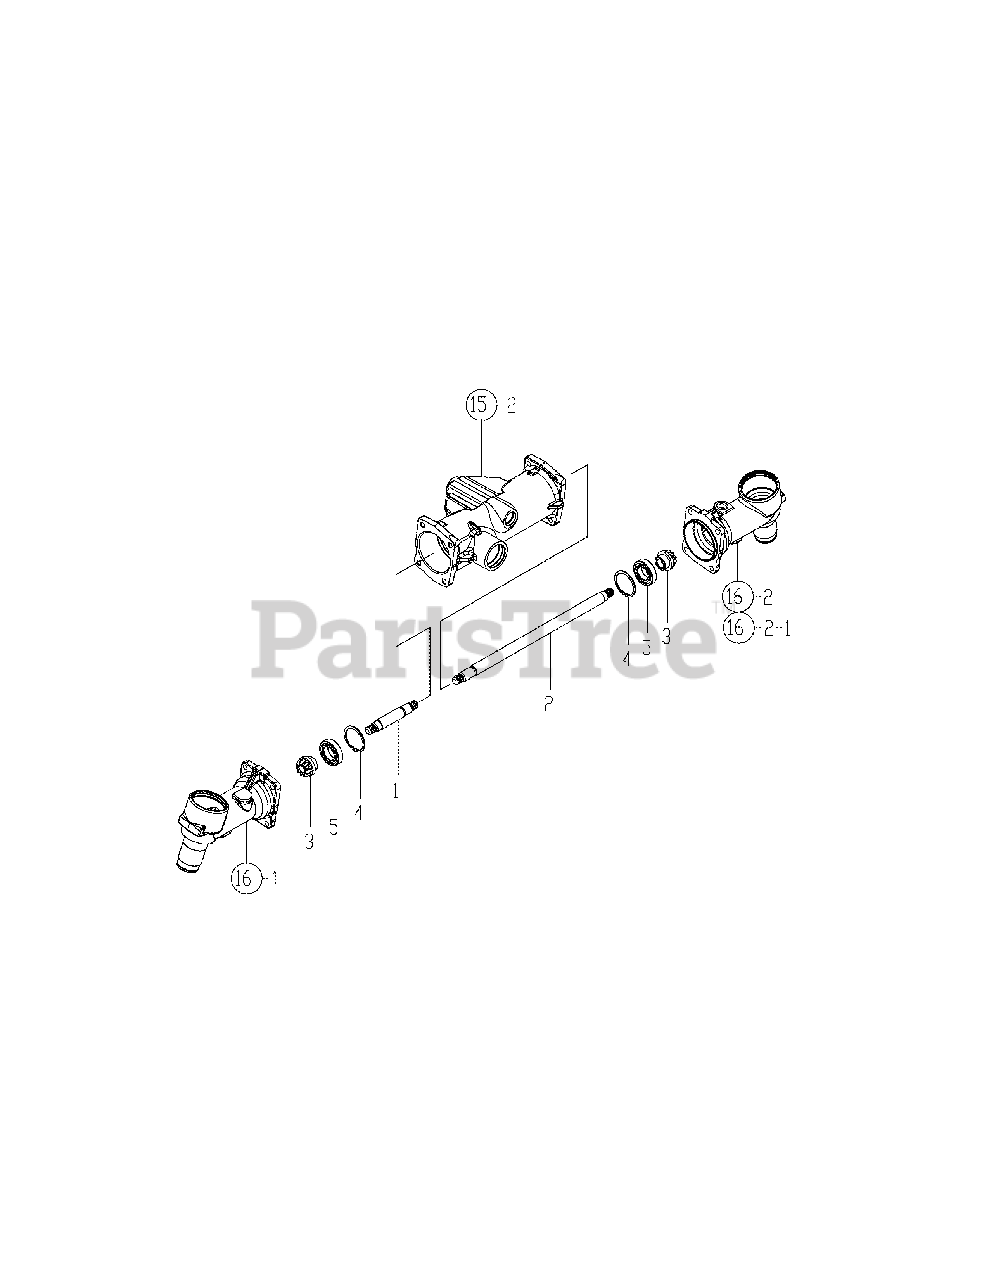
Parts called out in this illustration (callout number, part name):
1	Shaft L, Front 1
2	Shaft R, Front 1
3	Gear 9T, Bevel
5	Bearing, 6006 Ntn
